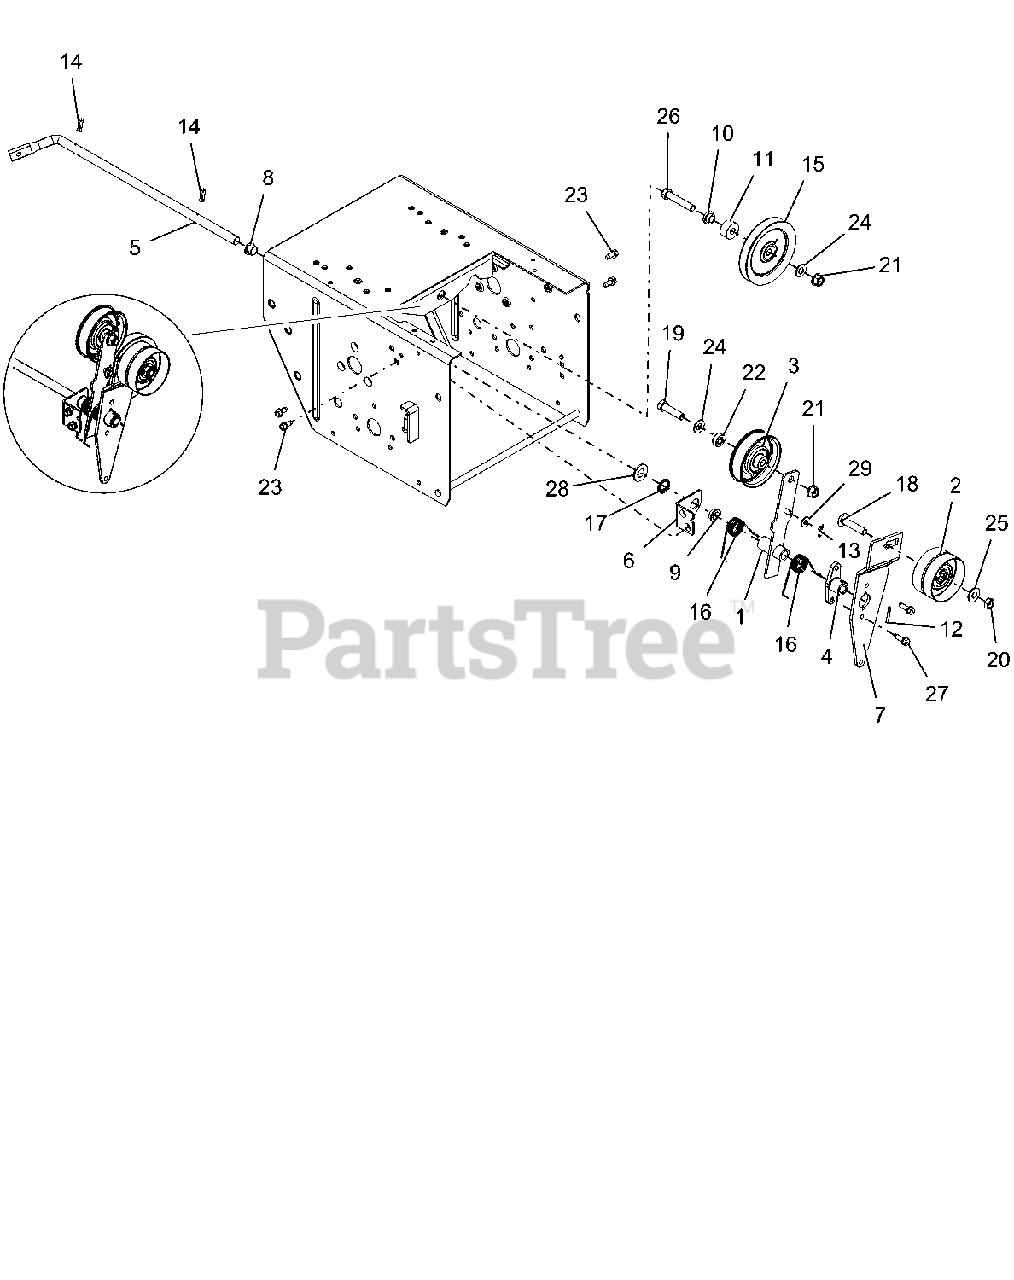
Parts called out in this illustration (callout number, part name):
1	ARM, TRACTION CLUTCH
2	IDLER, FLAT-2.75 OD X .375 ID
3	IDLER, FLAT - 3.05" X .75"
4	HUB, BRAKE ARM
5	ARM, ATTACHMENT
6	BRACKET, SUPPORT
7	ARM, IDLER-ATTACHMENT
8	BUSHING, POLYLINER-.50 SPLIT
9	BSHG,FLANGE .500X.625X.270X.75
10	BSHG, FLANGE .391X.56X.313X.75
11	BSHG,POCKET .391X.570X1.0X.450
12	PIN-ROLL .125X1.00
13	PIN-HAIR INT .06X.18X.77
14	CLIP, SPRING
15	SHV, .38"ID X 4.00"OD V-IDLER
16	SG-TORS .067X.88
17	WAVE SPRING .600X.875X.25FH
18	BLT-RHDSSQNK .38-16X1.75 G5YZ
19	BLT-HEX .38-16X1.50 GR5 YWZC
20	NUT-LK-CTR-JAM .375-16 YWZC
21	NUT-LK-TOP-FLG .38-16 YWZC
22	SPCR, BRG .315X.500X.358X.281
23	SCR-TAP .25-20X.50 HWH TR YWZ
24	WSHR-FL-STL.406X.812X.065 YWZ
25	WSHR-FL-STL.38X.875X.083 YWZC
26	BLT-HEX .38-16X2.00 GR5 YWZC
27	SCR-TAP-PM .25-20X.75 TR YWZ
28	WSHR-FL-STL.531X1.06X.095YWZC
29	WSHR-FL-STL.281X.62X.065 YWZC
